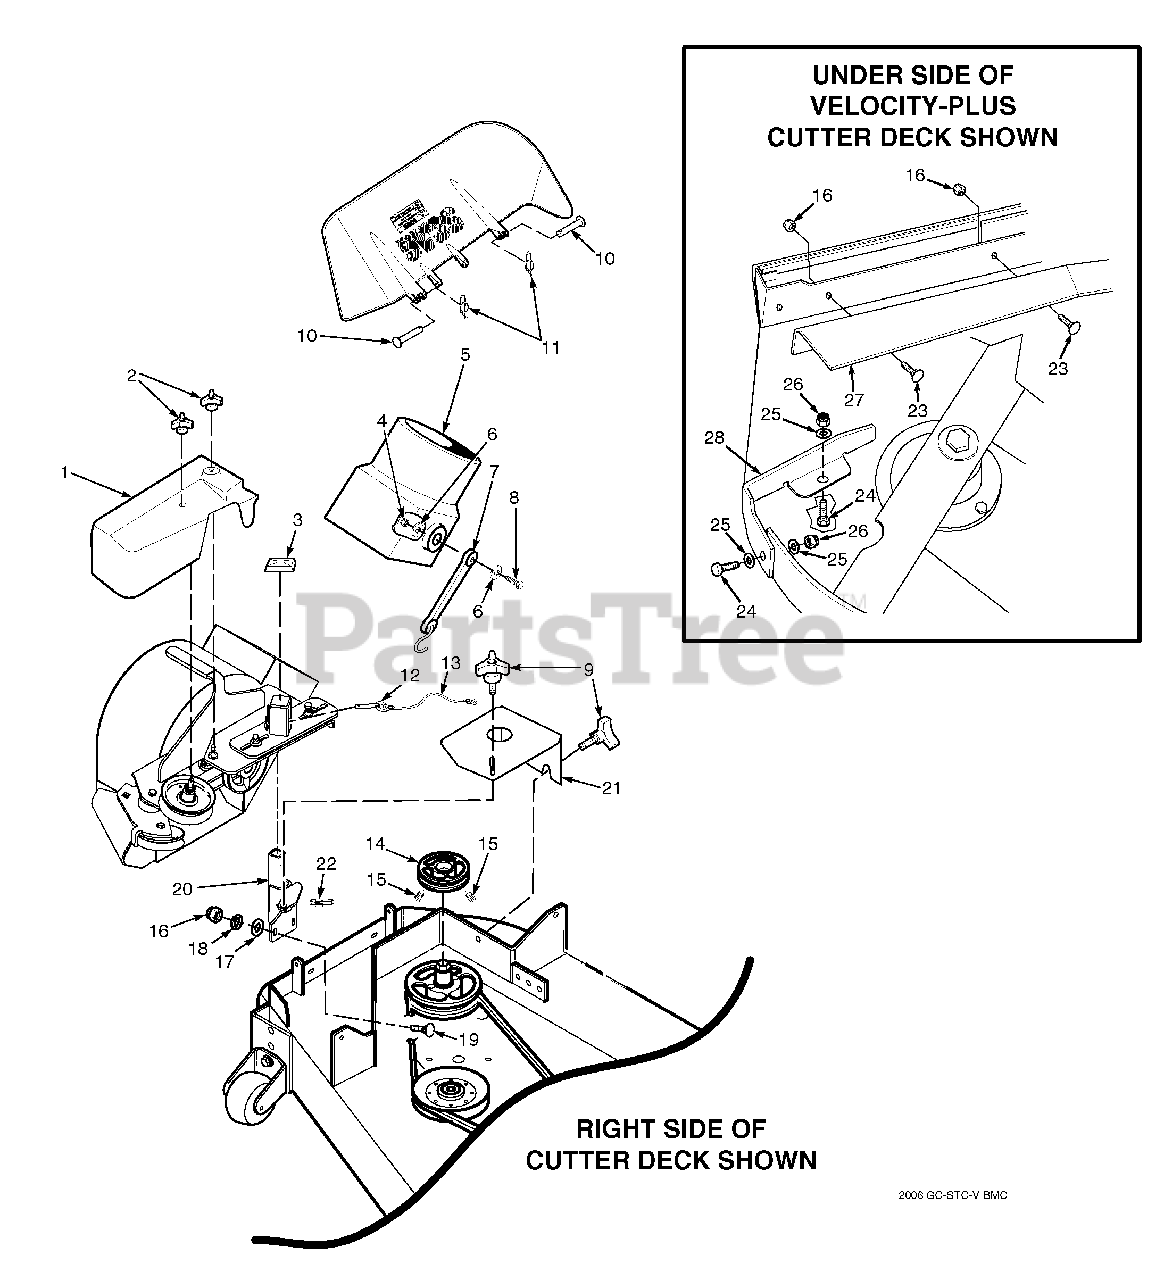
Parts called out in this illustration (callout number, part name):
1	Belt Cover, GC-STT - 61"
2	Wingnut, Plastic 3/8" Small
3	Cap, Square Vinyl
4	Nut, Elastic Stop 1/4-20
5	Adapter, Blower GC-STT
6	Flatwasher, 1/4-.312 x .750 x .065
7	Rubber Strap 7-3/4"
8	Bolt, Hex Head 1/4-20 x 1-1/4"
9	Knob W/Stud, 3/8-16 x 1-1/4"
10	Clevis Pin, 5/16 x 1-1/2"
11	Pin, Rue Cotter 5/16 Dia.
12	Pin, Ring 1/2 x 2-1/4"
13	Lanyard
14	Pulley, 5-1/2" for 61" Deck
15	Setscrew, 5/16-18 x 3/8"
16	Nut, Elastic Stop 3/8-16
17	Lockwasher, 3/8"
18	Flatwasher, 3/8-.391 x .938 x .105
19	Bolt, Carr. 3/8-16 x 1-1/4" Grade 5
20	Mounting Post Weldment, Blower - 61"
21	Belt Cover Assembly, GC-STT-61V w/Cap
21	Cap, Spindle
23	Bolt, Carriage 3/8-16 x 1"
24	Bolt, Hex Head 5/16-18 x 1"
25	Flatwasher, 5/16-.375 x .875 x .083
26	Nut, Elastic Stop 5/16-18
27	Baffle, Front
28	Baffle, Turbo
